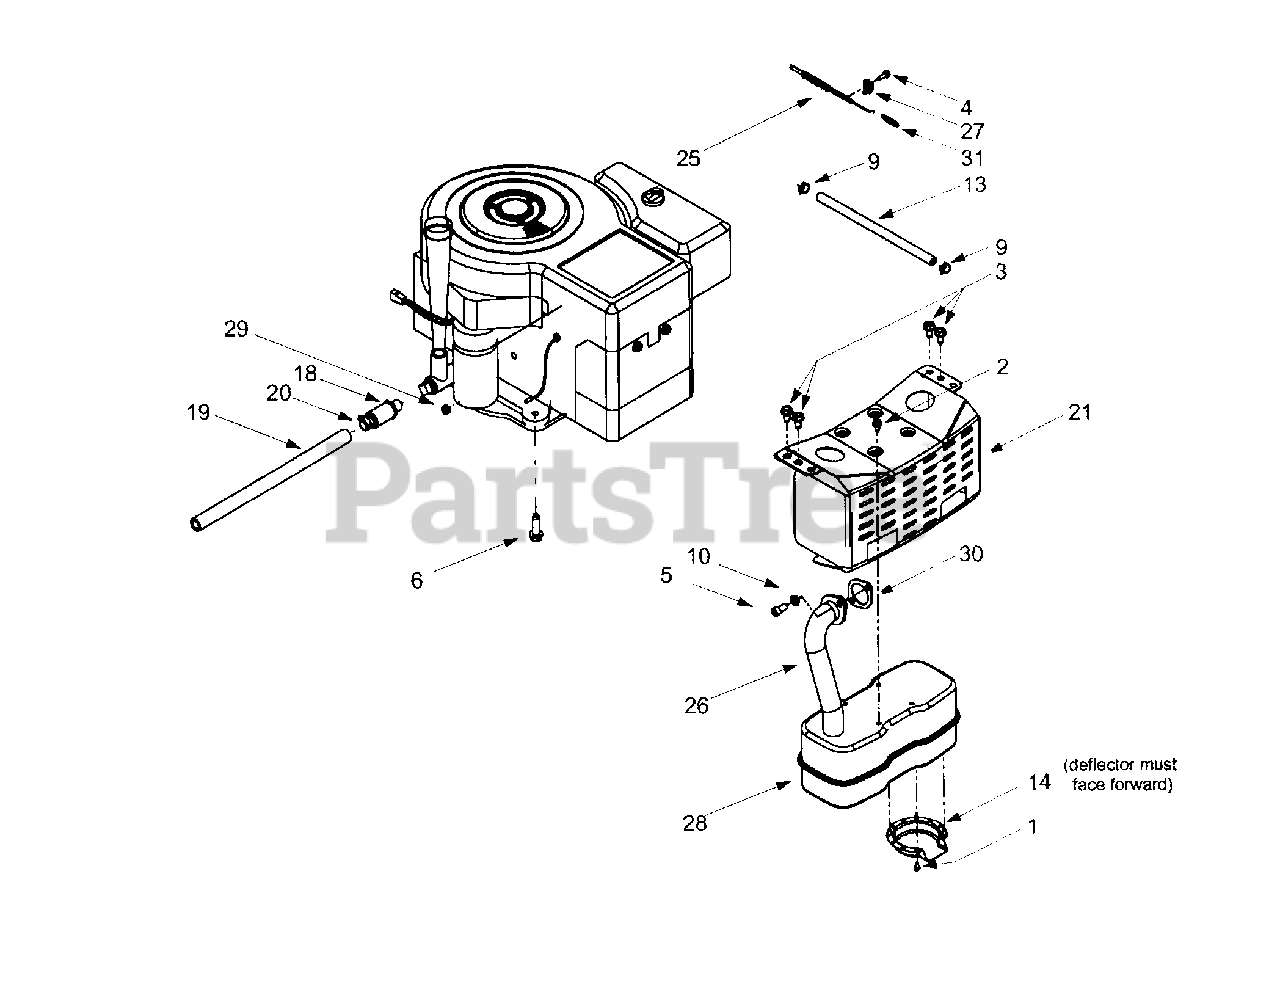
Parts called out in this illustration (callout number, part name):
1	Self-tapping Screw, #8-18 x.5
2	Self-tapping Screw, 1/4-20 x.5
3	Self-tapping Screw, 5/16-18 x .625
4	Screw, #10-32 x .625
5	Socket Cap Screw, 5/16-18 x .625
6	Self-tapping Screw, 3/8-16 x 1.25
9	Hose Clamp
10	Lock Washer, 5/16
13	Fuel Line Hose
14	Muffler Deflector
18	Oil Drain Valve
19	Oil Drain Hose
20	Oil Drain Cap
25	Throttle/Choke Cable
26	Exhaust Pipe
27	Casing Clamp
28	Muffler, Single Inlet
29	Hex Sems Nut, 1/4-20
30	Exhaust Gasket
31	Extension Spring, .275 x 1.25
